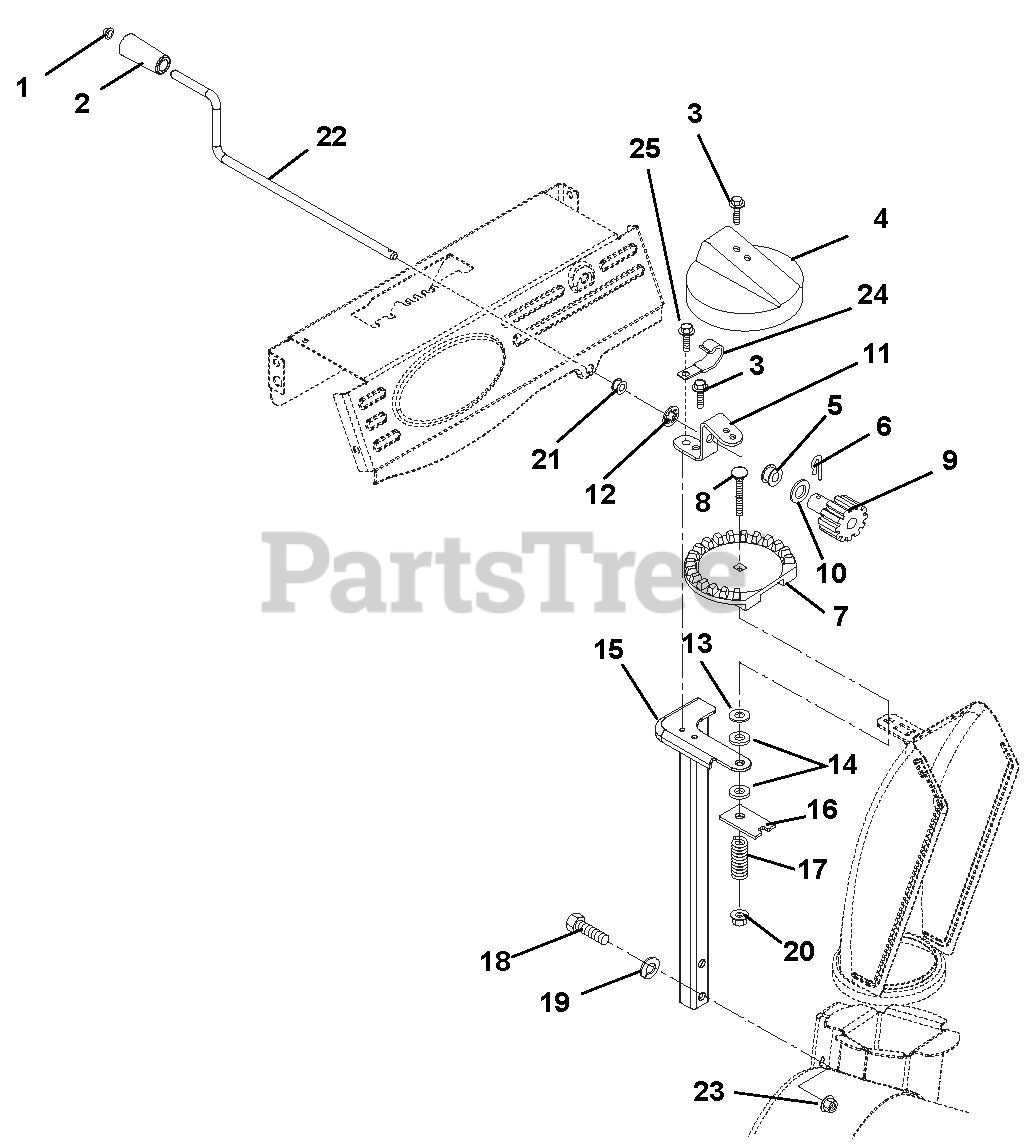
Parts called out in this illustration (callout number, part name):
1	CAP, 3/8 ROD YWZC
2	KNOB, CHUTE CRANK
3	SCR-TAP .25-20X.50 HWH TR YWZ
4	GEAR COVER
5	BUSHING, POLYLINER-.63 SNAPIN
6	PIN, SPRING CLIP
7	CHUTE GEAR
8	@BLT-RDHDSQNK .38-16X2.50 G5YZ
9	PINION GEAR W/BRACKET
10	WSHR-THRST .625 X 1.0 X .03
11	BRACKET, PINION GEAR
12	PUSHNUT .625
13	WSHR-FL-STL .380X1.50X.062 YWZ
14	FRICTION WASHER
15	CHUTE PEDESTAL, TALL COMPACT
16	PLATE, FRICTION
17	SG-COMP .187X.56X1.62
18	@BLT-HEX .38-16X1.75 GR5 YWZC
19	@WSHR-LK .38X.094 REG YWZC
20	@NUT-LK-TOP-FLG .38-16 YWZC
21	BUSHING, POLYLINER-.38 SNAPIN
22	CHUTE CRANK,COMPACT 920,XXX HI
23	NUT, THREADED INSERT .38-16
24	J-CLAMP
25	SCR-TAP .25-20X.50 LGHWH TR YZ
